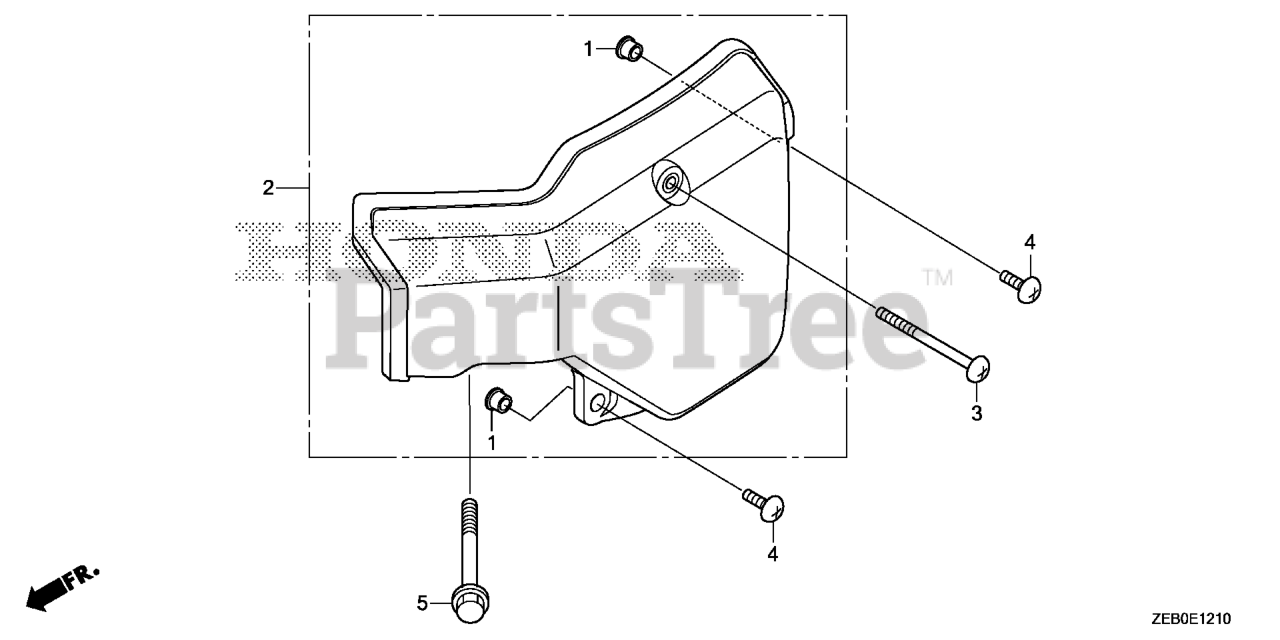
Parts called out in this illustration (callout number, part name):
1	COLLAR, FAN COVER
2	COVER (OUTER)
3	SCREW, TRUSS (6X55)
4	SCREW, TRUSS (6X16)
5	BOLT, FLANGE (6X55)
